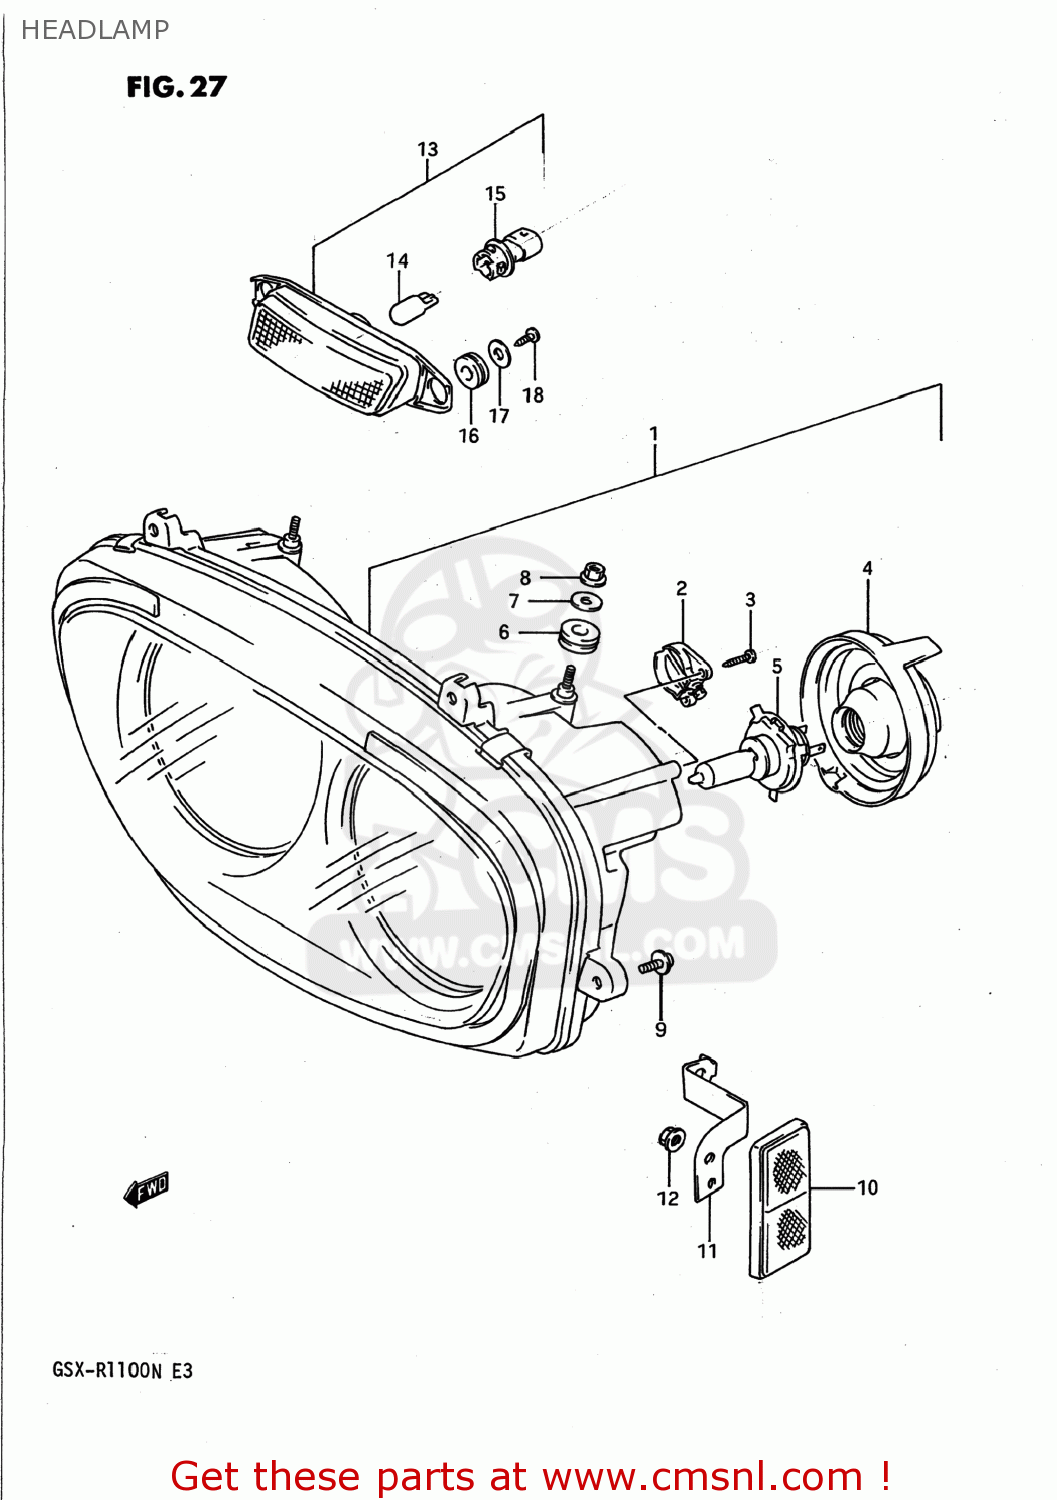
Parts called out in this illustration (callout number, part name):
1	HEADLAMP ASSEMBLY
2	GEAR UNIT ASSY,LWR
3	SCREW
4	COVER,SOCKET
5	BULB(12V60/55W,H4)
6	GROMMET
7	WASHER
8	NUT 6MM
9	SCREW
10	REFLEX REFLECTOR ASSEMBLY
11	BRACKET,FR SIDE RR,R
12	NUT
13	LAMP ASSY,FR POSITION
14	BULB(12V5W)
15	SOCKET ASSY
16	CUSHION
17	WASHER (4X16X1.2)
18	SCREW
